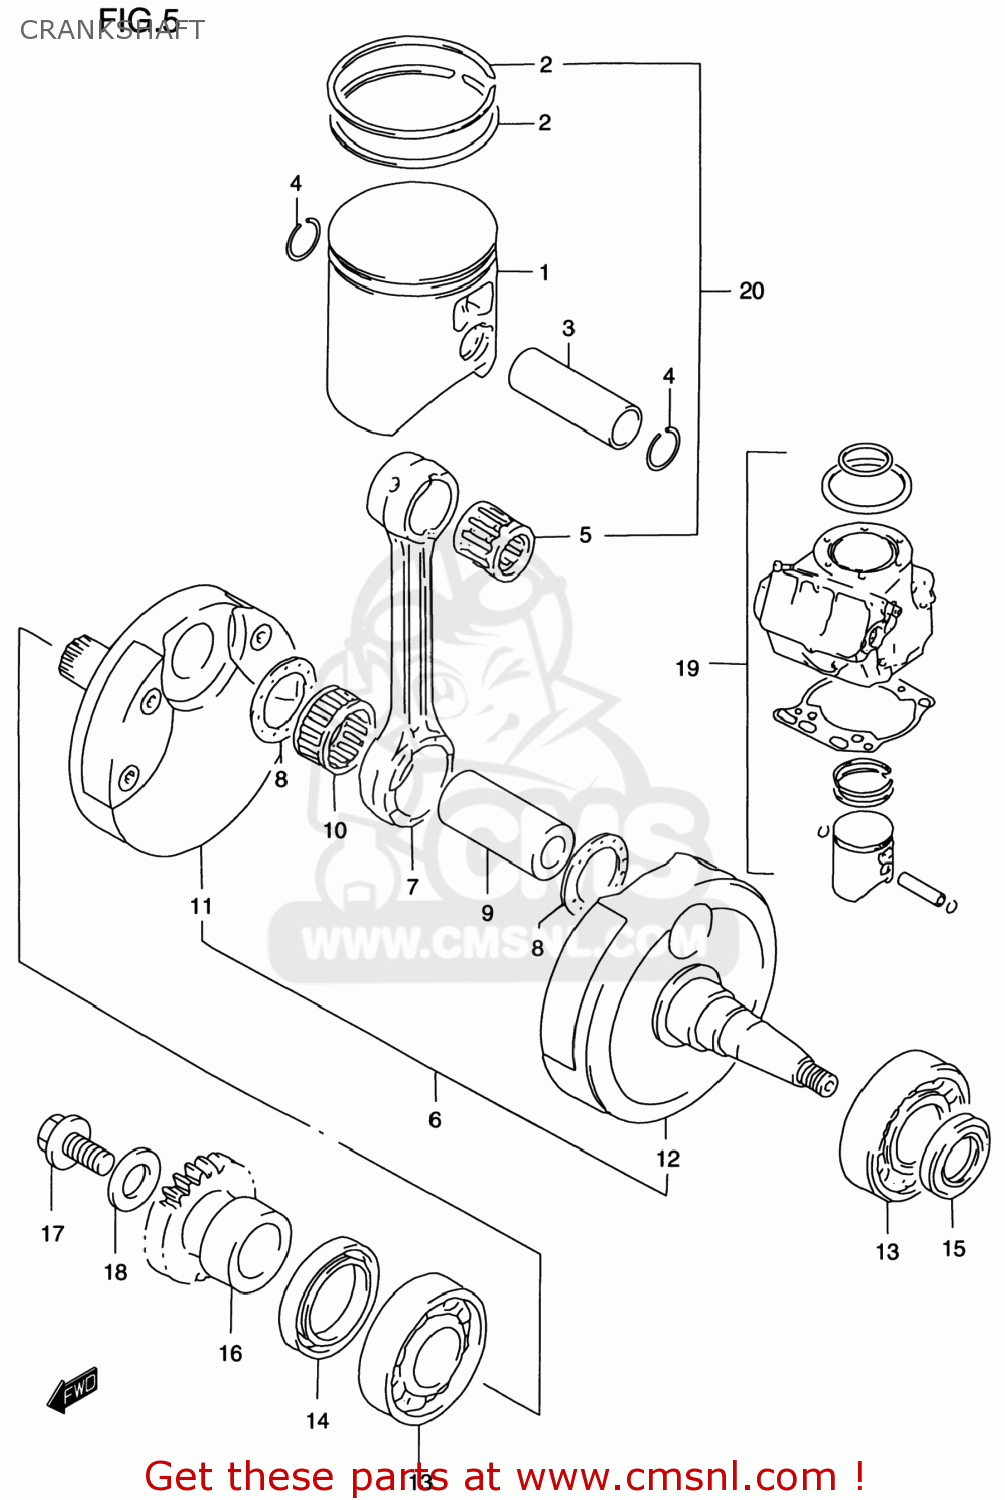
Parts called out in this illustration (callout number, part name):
1	PISTON
2	RING,PISTON
3	PIN,PISTON
4	CIRCLIP
5	BEARING(18X23X22)
6	CRANKSHAFT ASSEMBLY
7	CONNECTING ROD
8	WASHER(24X38.5X1.5)
9	PIN,CRANK
10	BEARING(24X30X20)
11	CRANKSHAFT,RIGHT
12	CRANKSHAFT,L
13	BEARING(28X68X18)
14	SEAL,OIL(38X52X8)
15	SEAL,OIL(25X37X7)
16	GEAR,PRIMARY DRIVE (NT:
17	BOLT,PRIMARY DRIVE GEAR
18	WASHER
19	TOP END KIT,ENGINE
20	PISTON KIT
